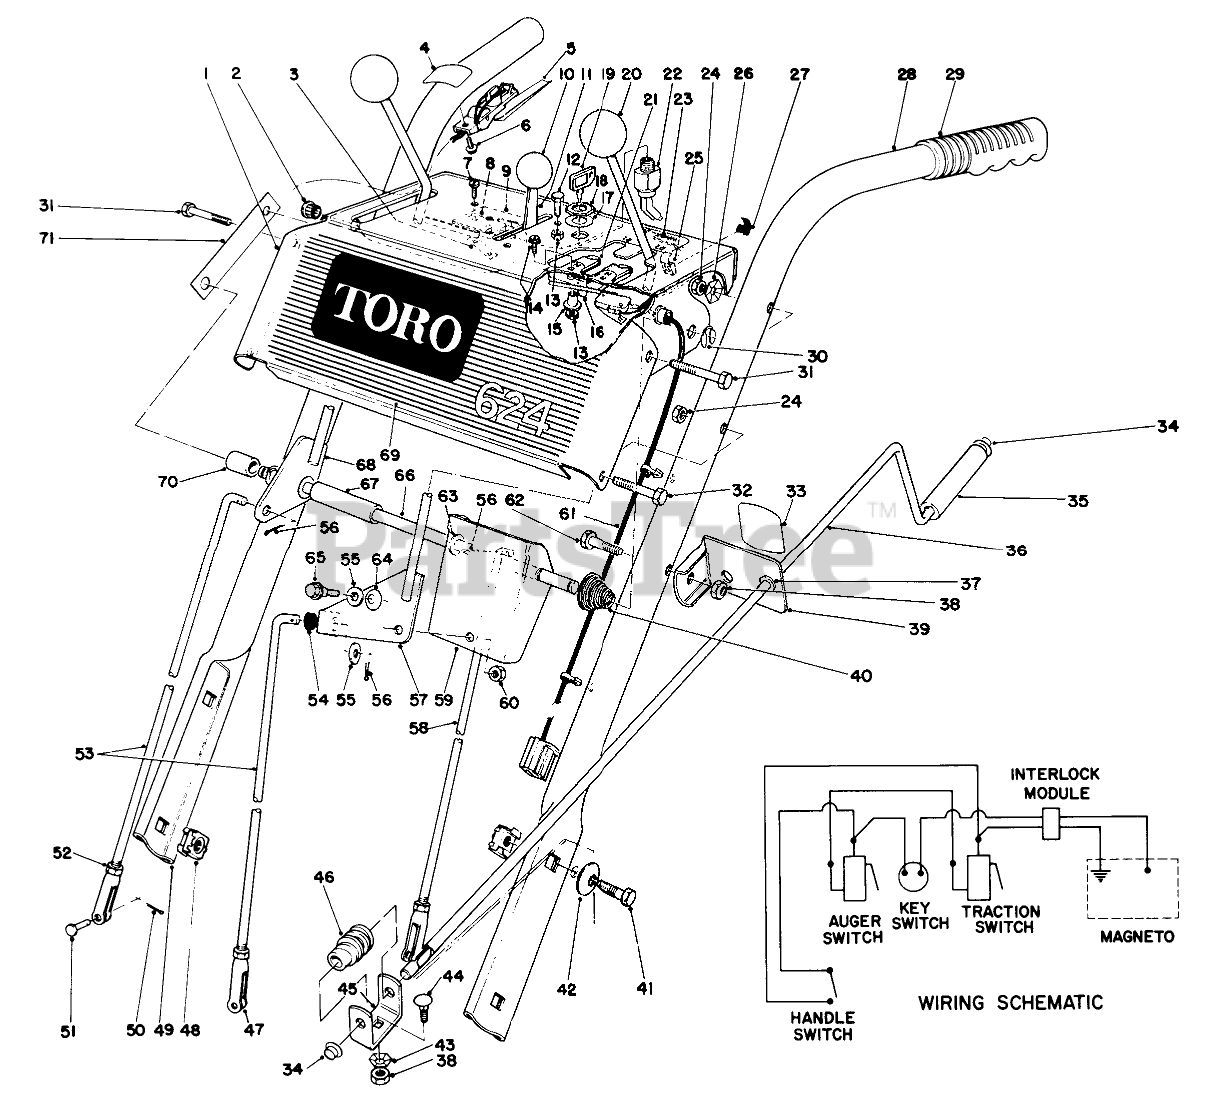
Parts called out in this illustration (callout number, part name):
1	ESCUTCHEON PLT B
2	BUSHING NYLON
3	NUT-SPEED
4	INTERLOCK DECAL
5	INTERLOCK HDLE SWITCH
6	SCREW
7	SCREW-SPH
8	SWITCH-MICRO
9	SWITCH MTG PAD
10	CONTROL KNOB
11	THROTTLE CONTROL
12	HEX HEAD SEMS 10-24X1/2
13	NUT-LOCK, NI
14	10-24 X 7/8 RND HD MS
15	INTERLOCK SPACER
16	INTERLOCK SPRING
17	WASHER-TOOTH, INTERNAL
18	NUT-HH
19	KEY-IGNITION
21	Slide Interlock
22	On-Off Switch (Incl. Ref. #17 & 18)
23	INSTR DECAL
24	NUT-LOCK, CONE
25	WIRE CLAMP
26	Washer
27	Mounting Stud
28	LEFT HANDLE
29	Grip Handle
30	RING-CLIP
31	SCREW-HH
32	SCREW-HH
33	DECAL-CHUTE DIRECTION
34	RETAINER-PUSH ON
35	Grip-Rod
36	CHUTE CONTROL ROD
37	Bushing
38	NUT-LOCK, NI
39	Chute Control Rod Mounting (Incl. Ref. #33 & 37)
40	CONICAL SPRING
41	SCREW-HH
42	WASHER-SPRING
43	WASHER-LOCK
44	BOLT-CARR
45	BRACKET-WORM
46	GEAR-WORM, CHUTE
47	CLEVIS
48	Retained Nut
49	HANDLE RIGHT
50	PIN-COTTER
51	PIN-CLEVIS
52	NUT-HJ
53	SPEED SELECTOR ROD
54	GROMMET-RUBBER
55	WASHER-FLAT
56	PIN-COTTER
57	SHIFT LEVER WA
58	TRACTION CONTROL ROD
59	SHIFT BRACKET
60	NUT-LOCK, CONE
61	WIRE HARNESS INTERLOC
62	SCREW-HH
63	WASHER-FLAT
64	7/16 SPRING WASHER
65	SHOULDER SCREW
66	PIVOT ROD
67	SHIFT LEVER SPACER
68	LEVER WA
69	DECAL - ESCUTCHEON 624
70	AUGER LEVER SPACER
71	ESCUTCHEON SUPT STRAP
